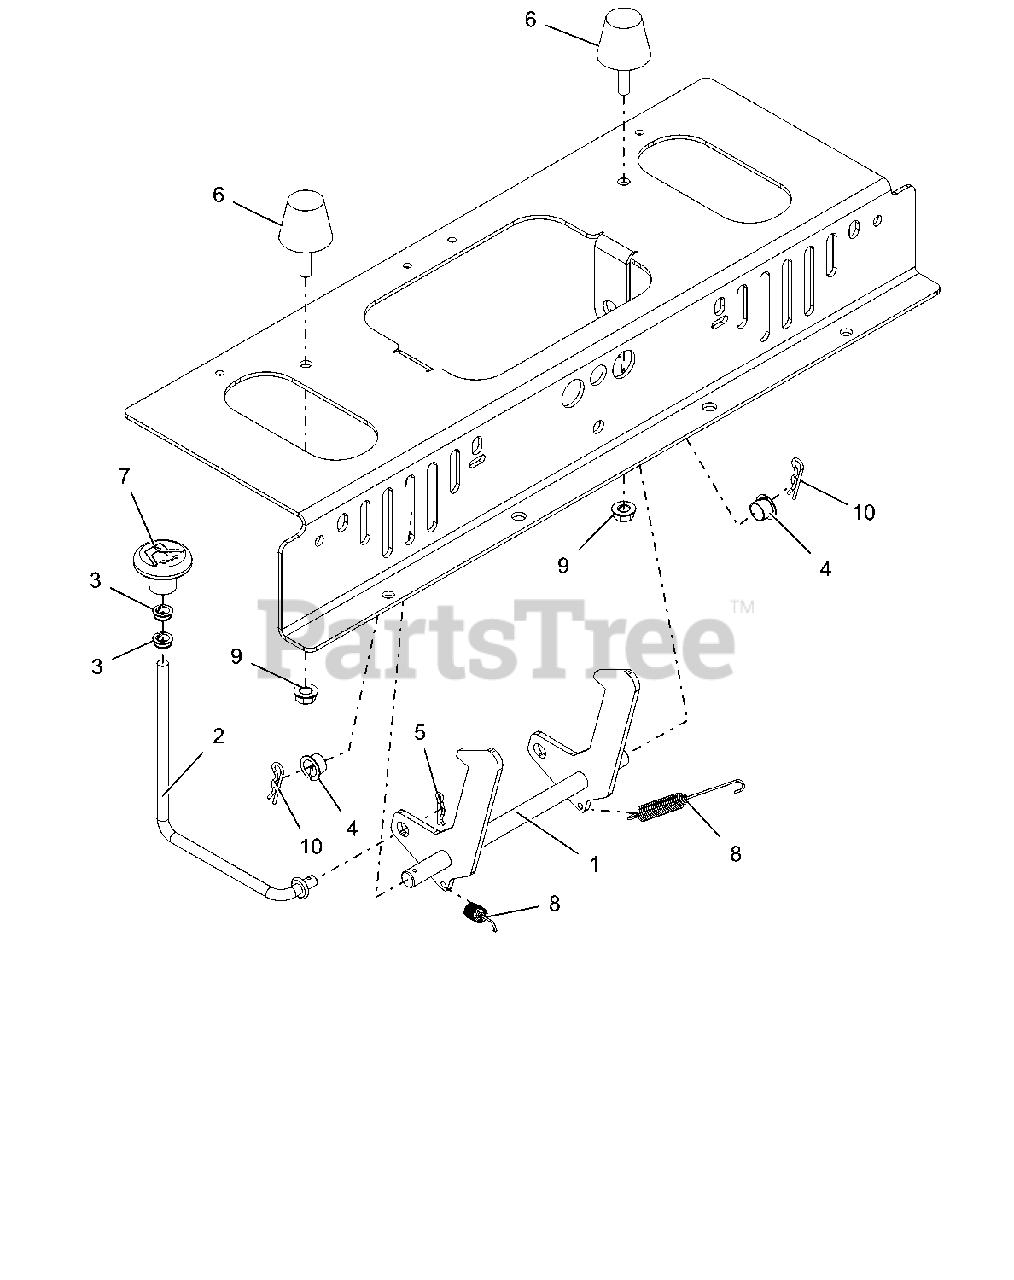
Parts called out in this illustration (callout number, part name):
1	WMT, SEAT LATCH (BLACK)
2	LINKAGE, SEAT RELEASE
3	BSHG, POLYLINER-.38 SNAPIN
4	BUSHING, POLYLINER - .50 SPLIT
5	PIN-HAIR, ENDRIES #25 YWZC
6	BUMPER, STUD MOUNTED CONE SHAPED
7	KNOB, PUSH/PULL
8	SPRG, EXTENSION
9	@NUT-SPNLK-FLG .312-18 YWZC
10	PIN-HAIR INT .08X.38X1.42 YWZC
